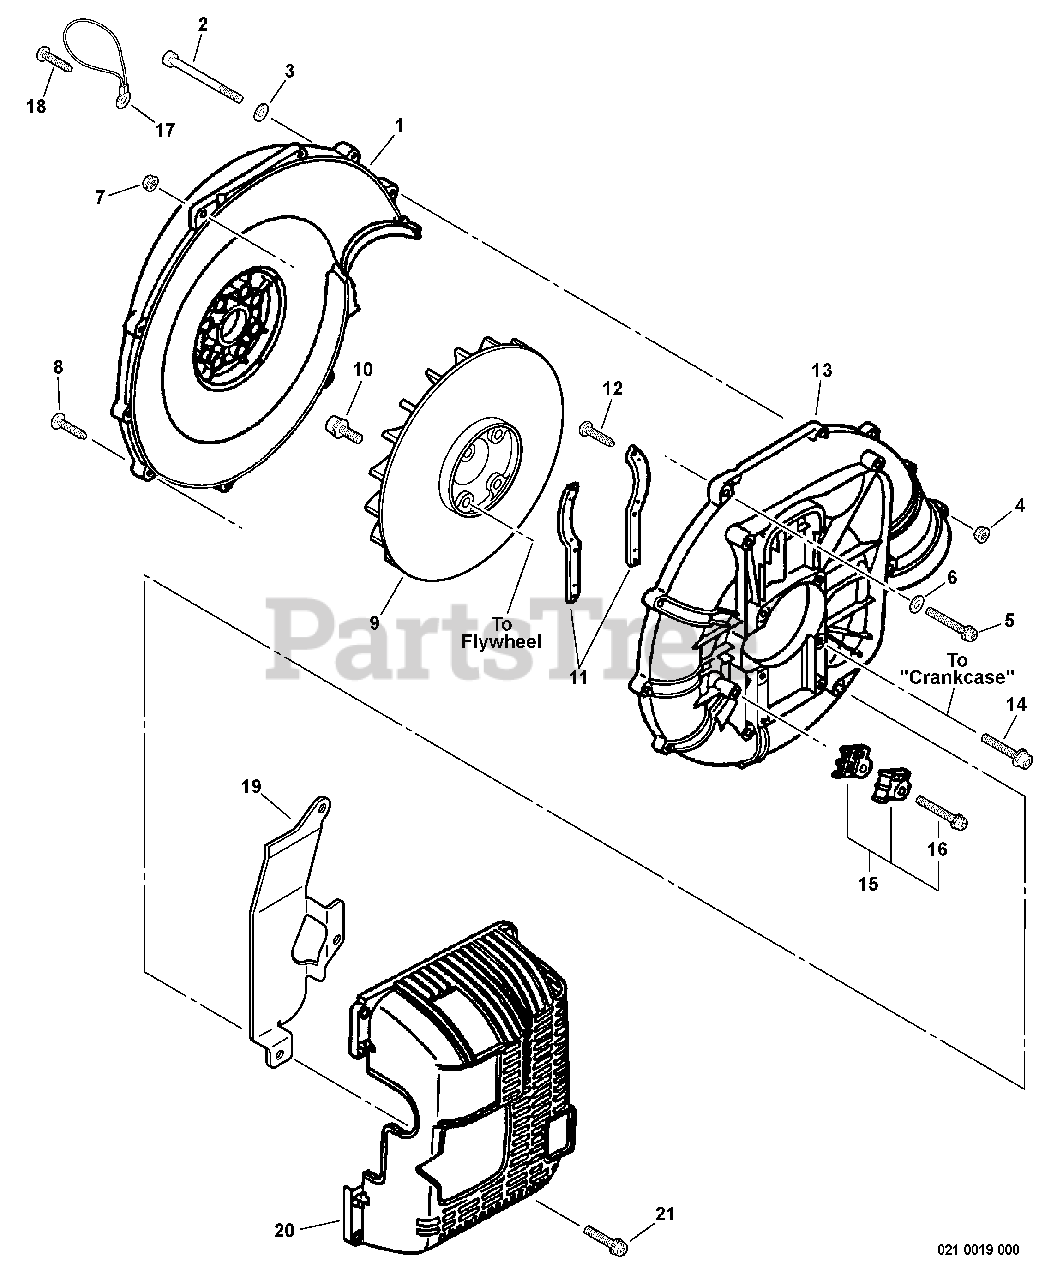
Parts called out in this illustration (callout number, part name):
1	COVER, FAN - INNER
2	BOLT 5×60
3	WASHER, FLAT 5.5×10×0.8
4	NUT, FLANGE M5
5	SCREW 5×40
6	WASHER 5.5×16×2T
7	NUT, FLANGE M5
8	SCREW 5×30
9	FAN
10	BOLT 5×20
11	BRACKET, ENGINE
12	SCREW TAPPING 3×12
13	COVER, FAN - OUTER
14	SCREW 5×32
15	CABLE HOLDER KIT
16	SCREW 5×25
17	STRAP, SAFETY
18	SCREW 5×16
19	INSULATOR
20	COVER, ENGINE
21	SCREW 5×18
